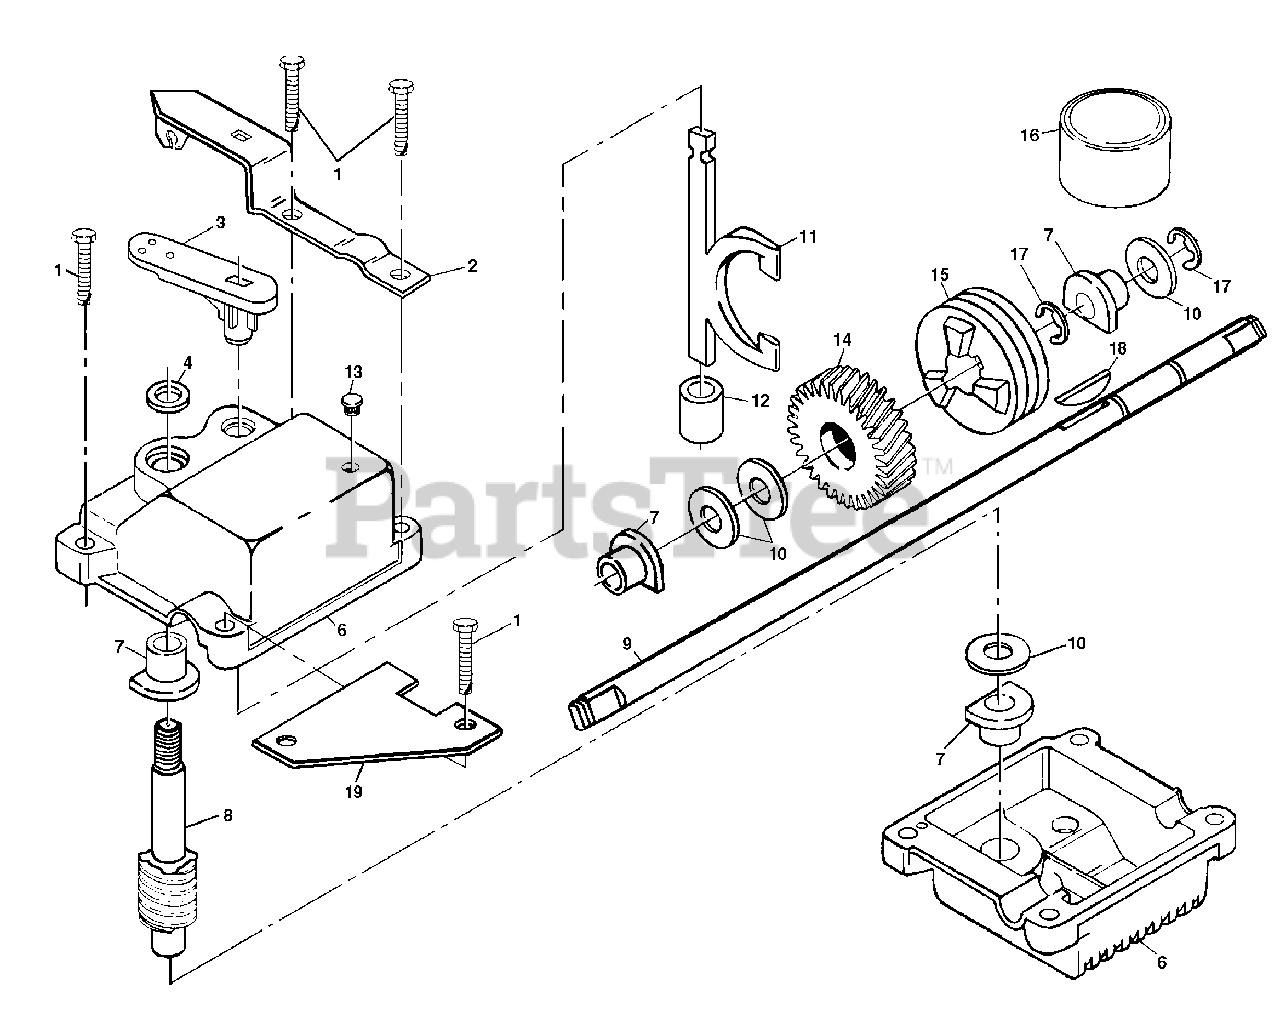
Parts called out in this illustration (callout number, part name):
1	Tapping Screw 1/4-20 x 1-1/4
2	Engagement Bracket
6	Gear Case Halves Kit
8	Worm Shaft
9	Drive Shaft
10	Hardened Washer
11	Clutch Yoke
14	Helical Gear
15	Clutch Jaw
16	Grease
18	Hi-Pro Key
19	Spring Bracket
